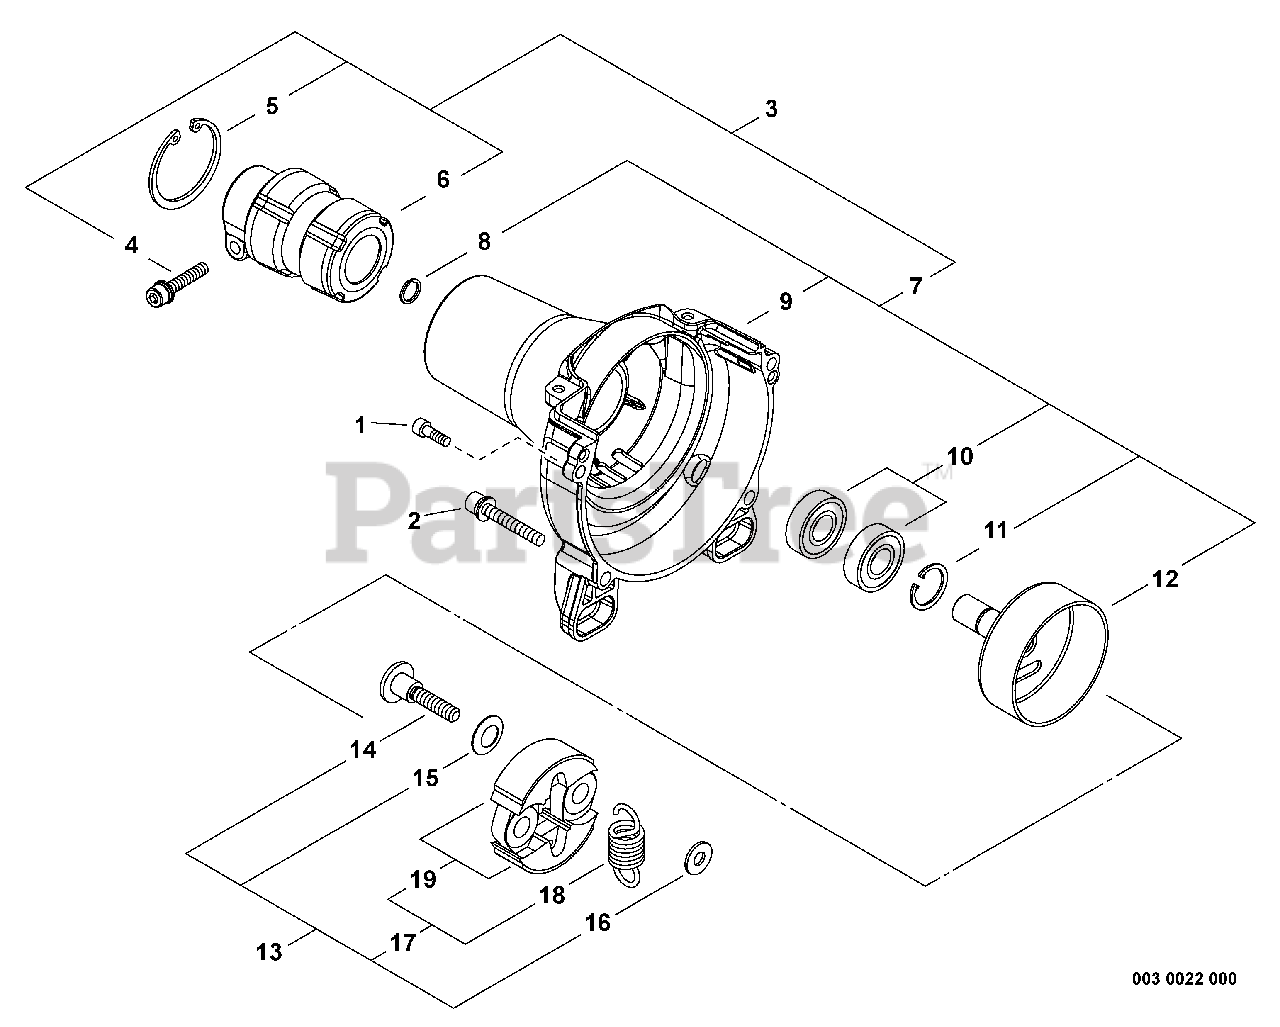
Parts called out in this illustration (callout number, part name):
1	SCREW - 5X16
2	SCREW - 5X45
3	FAN CASE ASSY
4	SCREW - 5X22
5	RING, RETAINING - 42
6	CLAMP, MAIN PIPE
7	FAN COVER KIT
8	RING, RETAINING
9	COVER, FAN
10	BEARING, BALL - 6000ZZ
11	RING, RETAINING - 26
12	DRUM, CLUTCH
13	CLUTCH ASSY
14	BOLT, CLUTCH
15	WASHER - SPRING
16	WASHER - 6
17	CLUTCH ASSY
18	SPRING, CLUTCH
19	CLUTCH SHOE SET
